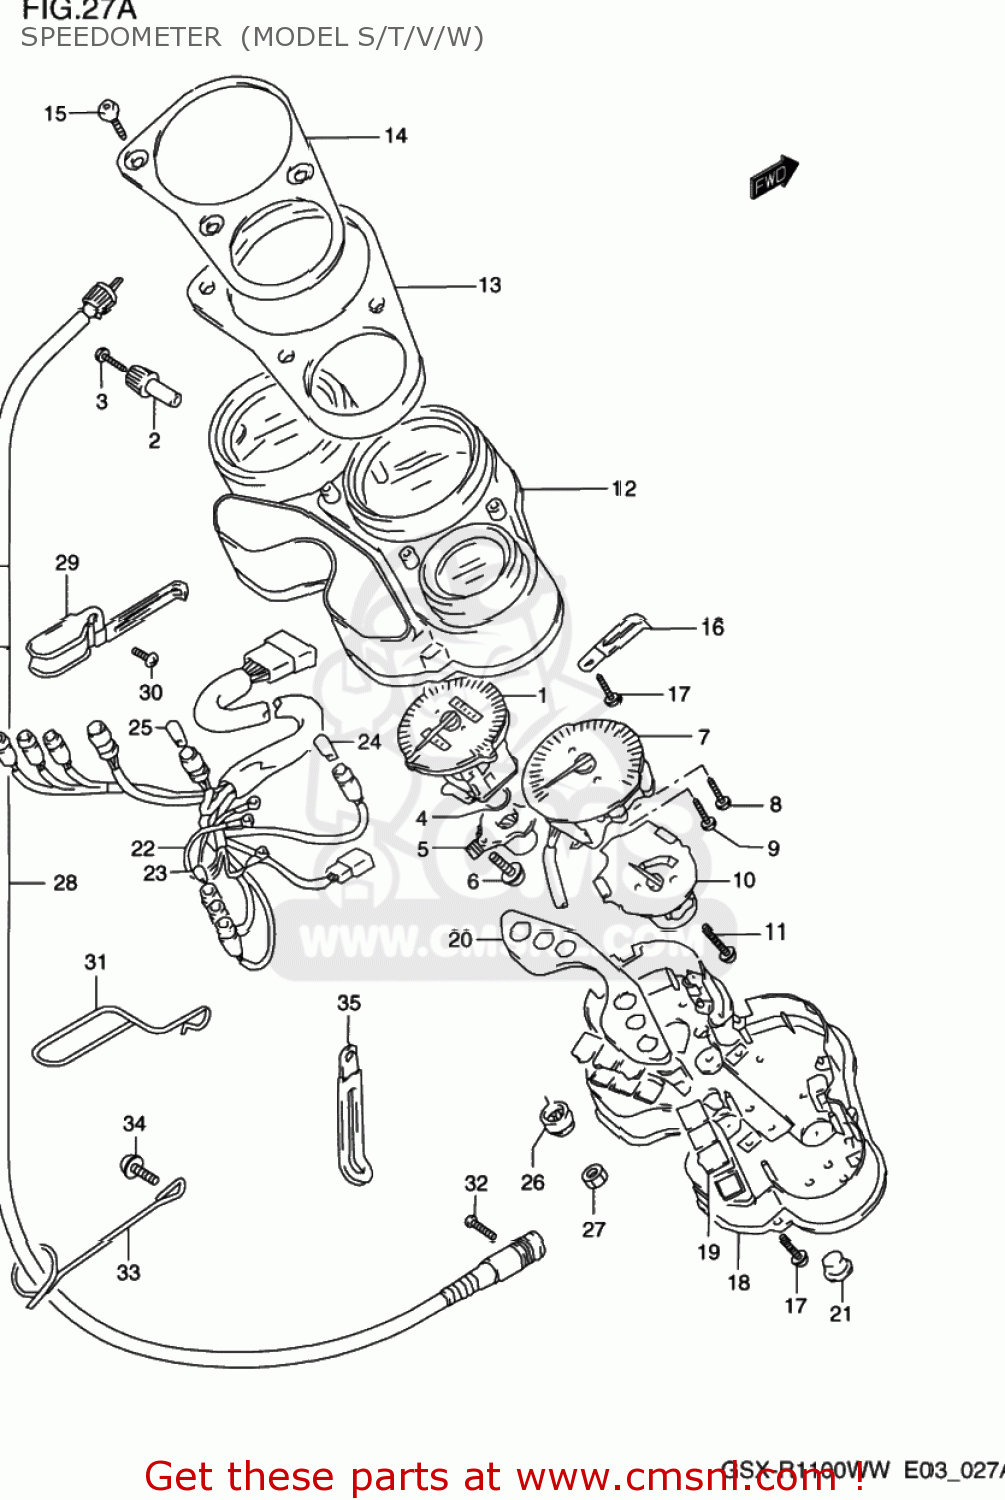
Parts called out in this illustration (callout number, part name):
1	SPEEDOMETER(MILE/KILO)
2	KNOB,TRIP
3	SCREW(2X6)
4	O RING
5	BOX,GEAR
6	SCREW
7	TACHOMETER
8	SCREW(4X22)
9	SCREW
10	METER,TEMPERATURE
11	SCREW(3X22)
12	HOOD
13	CUSHION
14	PANEL,METER
15	SCREW
16	CLAMP(L:45)
17	SCREW
18	CASE,METER
19	LENS SET
20	PANEL
21	CAP
22	SOCKET
23	BULB(12V3W,T6.5)
24	BULB(12V1.7W,T6.5)
25	BULB(12V1.7W,T10,WB121)
26	CUSHION,METER
27	NUT
28	CABLE ASSY,SPEEDOMETER
29	GUIDE,METER CABLE NO.1
30	SCREW 5X8
31	GUIDE,METER CABLE NO.2
32	SCREW
33	GUIDE,SPEEDOMETER CABLE,R
34	SCREW 6X10
35	CLAMP(L:65)
